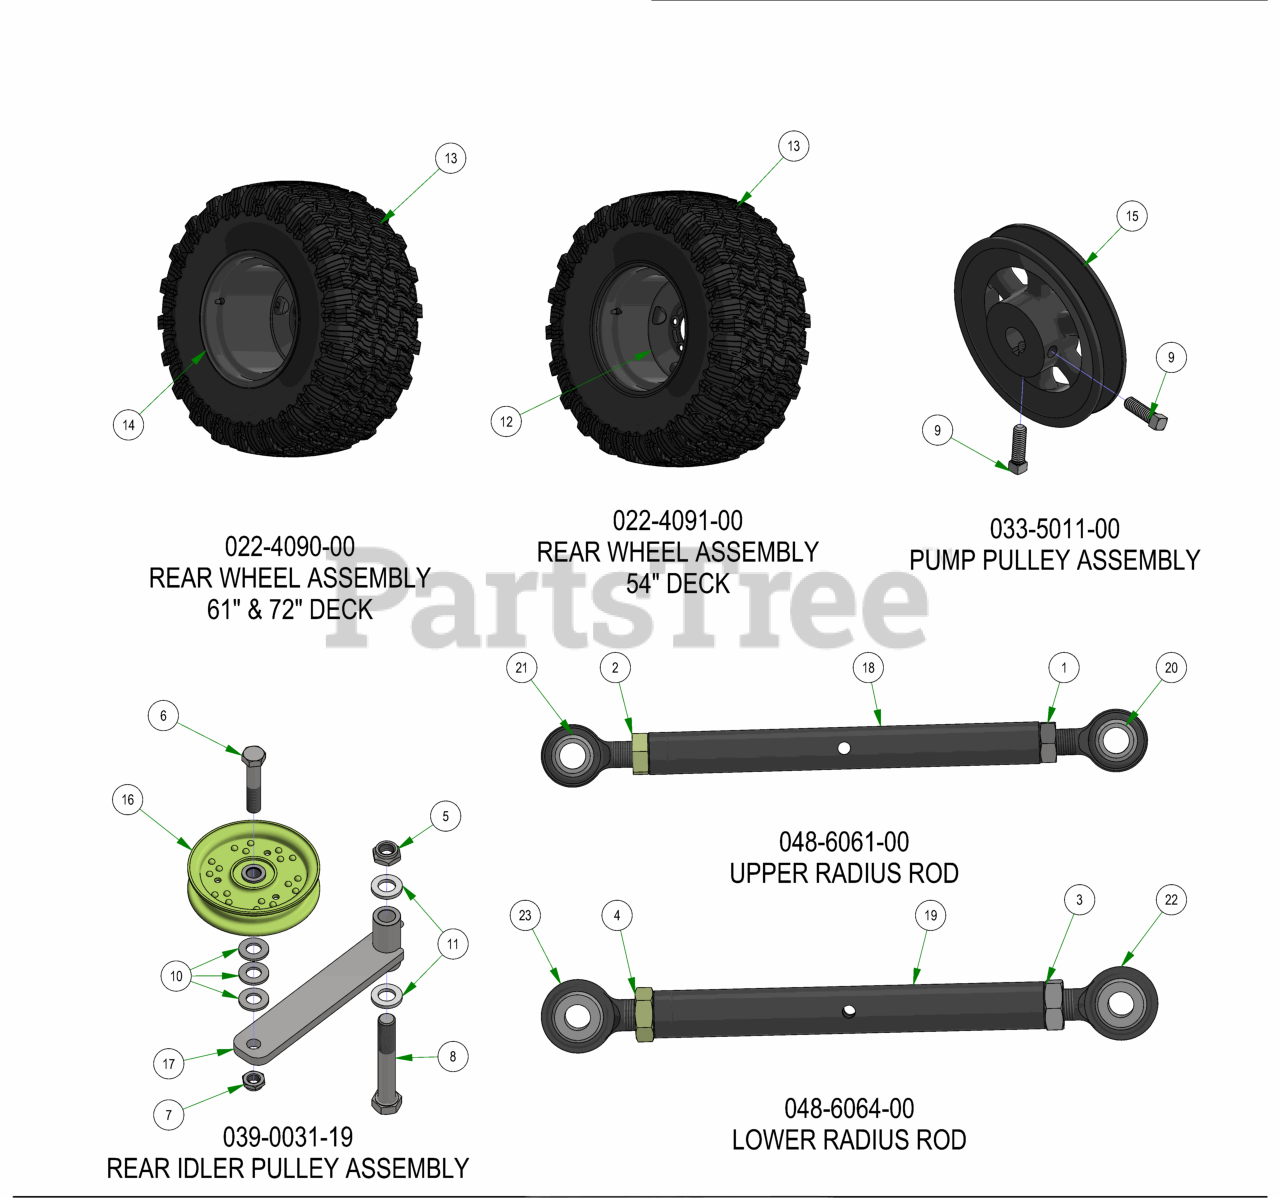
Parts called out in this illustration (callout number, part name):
1	5/8-11 HEX JAM NUT ZINC
2	NUT, 5/8-18LH
3	3/4-16 HEX JAM NUT ZINC
4	3/4-16 LH HEX JAM NUT ZINC
5	5/8-11 NYLON INSERT JAM LOCKNUT ZINC
6	1/2-13 X 2-1/2 HEX CAP SCREW GR 5 ZINC
7	1/2-13 NYLON INSERT JAM LOCKNUT ZINC
8	5/8-11 X 4 HEX CAP SCREW (GR.8) ZINC YELLOW
9	Square-Head Cup-Point Set Screw 5/16''-18
10	1/2 SAE FLAT WASHER (1-1/16" OD) GR.8 ZINC YELLOW
11	.635 ID X 1.120 OD X .140 THICK FLAT WASHER NYLON
12	12x8.5 Black Wheel
13	2019 26x12-12 Reaper Turf Tire
14	2019 10.5" Wheel
15	5" Pump Pulley
16	4 3/4 Idler Pulley - ABFI-76
17	2019 Vertical Suspension Drive Tensioner
18	2019 Suspension Link Body
19	Rear Radius Rod, 3/4 Body
20	2019 RH 5/8" Heim
21	2019 LH 5/8" Heim
22	3/4-16 x 5/8 RH Heim
23	3/4-16 x 5/8 LH Heim
